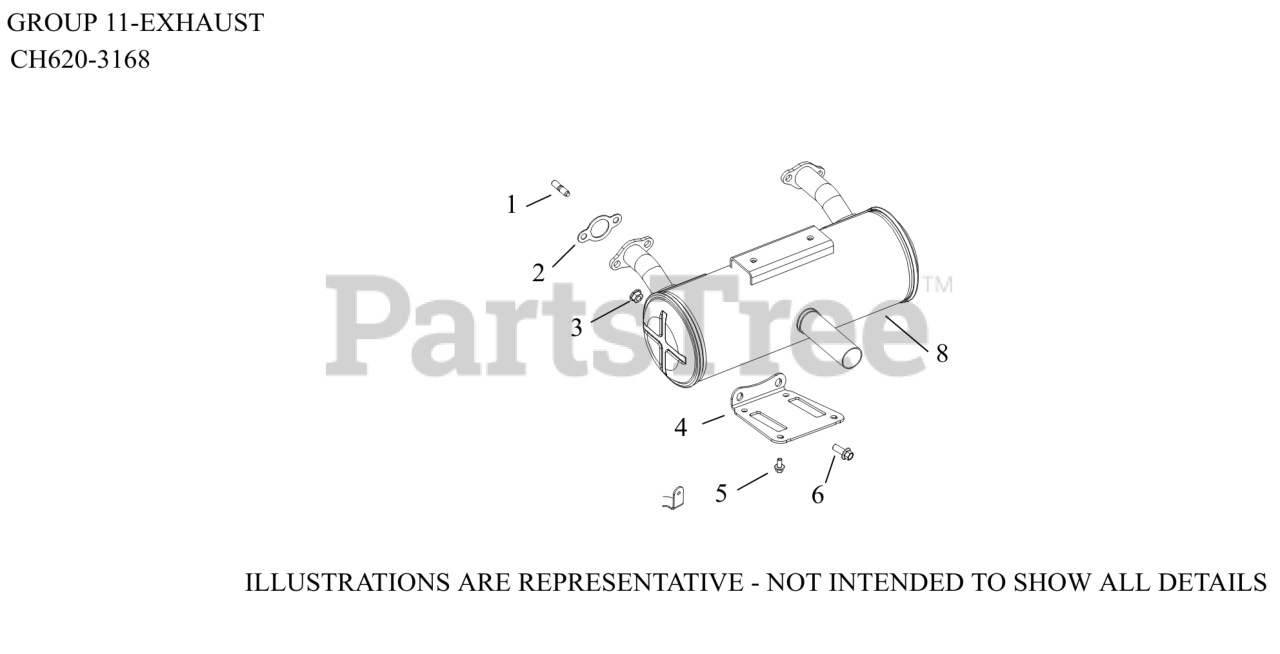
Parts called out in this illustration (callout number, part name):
1	STUD, METRIC EXHAUST
2	GASKET, EXHAUST
3	NUT, FLG M8X1.25
4	BRACKET, MUFFLER
5	SCREW, FLG M6X1.0X12
6	SCREW, FLG M8X1.25X20
